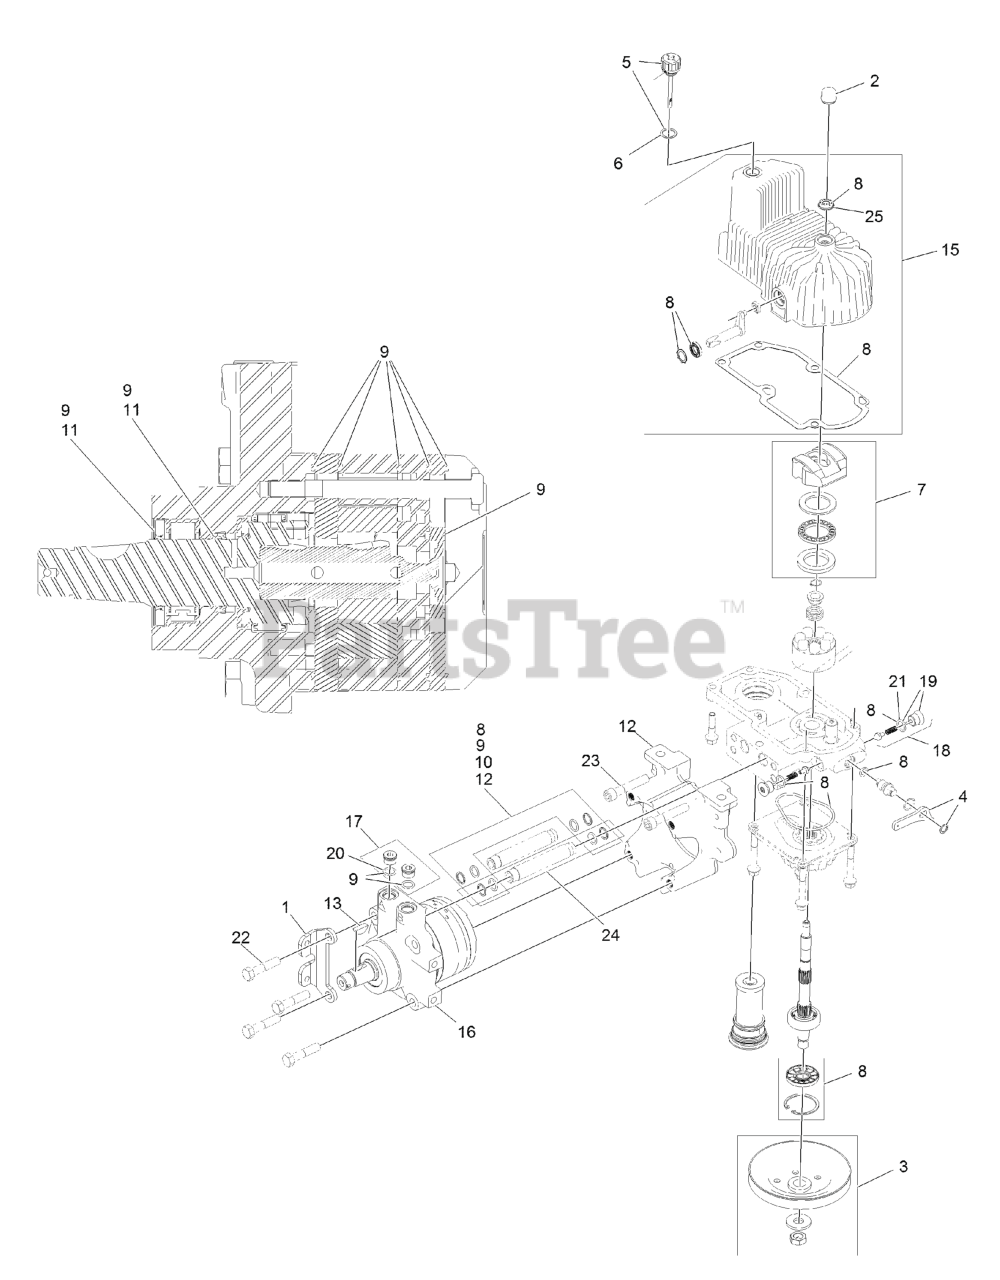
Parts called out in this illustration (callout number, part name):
1	MOUNT-SHOE, HORSE
2	FAN KIT
3	PULLEY KIT
4	HANDLE-BYPASS VALVE, HYDRO
5	DIPSTICK-HYDRO W/GASKET
6	GASKET-DIPSTICK, HYDRO
7	SWASH BLOCK KIT
8	PUMP SEAL KIT
9	MOTOR SEAL KIT
10	TUBE SEAL KIT
11	OUTPUT SHAFT SEAL KIT
12	NOSE CUP-UHT
13	KEY-WOODRUFF
15	HOUSING-HYDRO, RH
16	MOTOR-HYDRAULIC RH 240CC
17	MAGNETIC PLUGS SERVICE KIT
19	O-RING-CHECK VALVE
20	SCREW HH
21	SCREW-HSH
22	HYDRAULIC TUBE KIT
23	SHOCK VALVE, 12CC HYDRO
24	SEAL-FAN DRIVE
25	Kit, Pump Section 12Cc RH
26	KIT, ROTATING GRP 12CC RH
